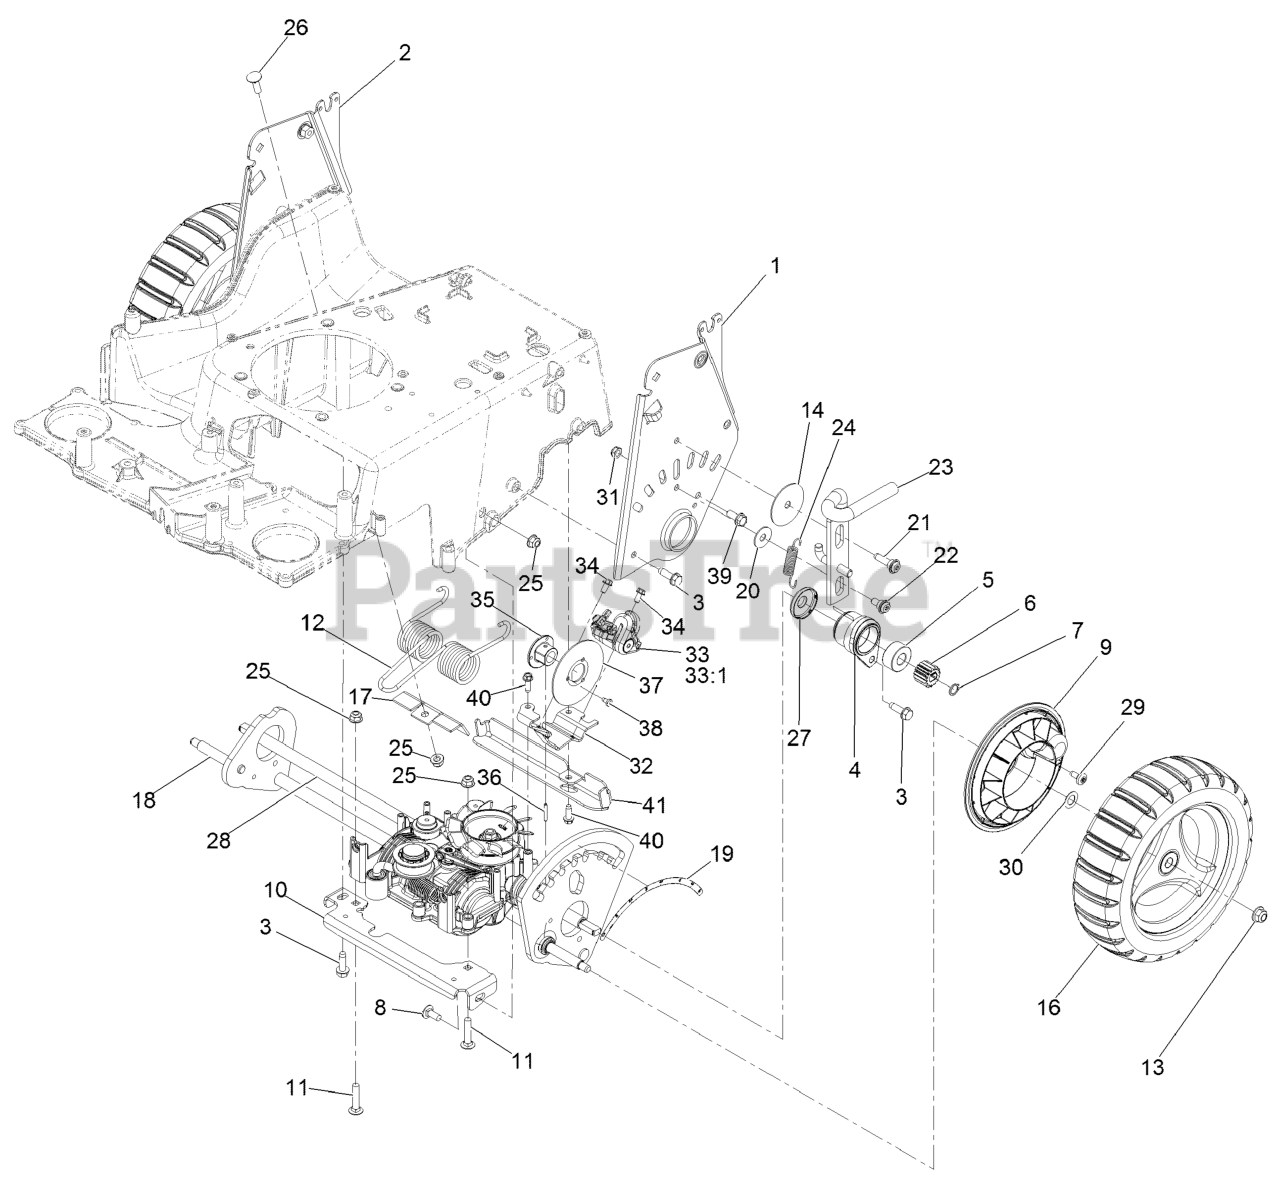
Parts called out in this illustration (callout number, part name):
1	HOC Plate Assembly
2	HOC Plate Assembly
3	SCREW-THD ROLL, HWH
4	Bearing Retainer ASM
5	BEARING-BALL, CUSTOM
6	GEAR-PINION, 15T
7	RING-RETAINING
8	SCREW-CARR
9	Cover-Wheel
10	Bracket-Transmission, Front
11	BOLT-CARR
12	SPRING-TORSION
13	NUT-HF, NI
14	WASHER-PLAIN
16	WHEEL ASM, 10.5 W/GEAR
17	BRACKET
18	REAR AXLE ASM
19	DECAL-HOC, REAR
21	SCREW-SHOULDER, BHTF
22	BOLT-SHOULDER
23	LOCK-HEIGHT, ADJ
24	Wheel ASM, 10.5 W/Gear
25	NUT-HF, NI
26	BOLT-CARR
27	COVER-BEARING
28	TRANSMISSION-MV702
29	SCREW-SHOULDER
30	WASHER-PLAIN
31	NUT-LOCK, NI
32	Bracket-Mount, Brake
33	CALIPER-BRAKE, DISC
34	SCREW-HWH
35	Hub-Rotor
36	Pin-Roll
37	Disc-Rotor
38	SCREW-TORX PH THD ROLL
40	SCREW-HWHTF
41	Bracket-Support, Cable
